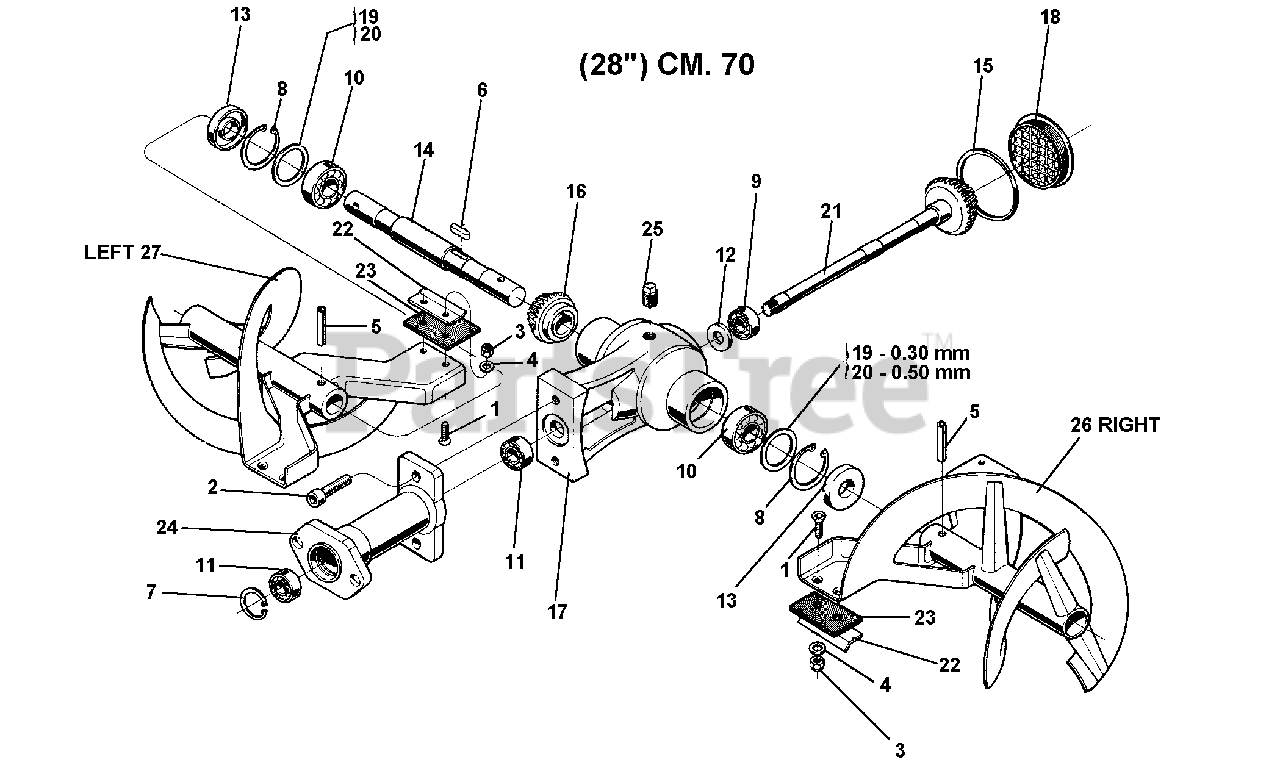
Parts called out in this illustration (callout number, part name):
1	SCREW M6 X 25
2	SCREW TCCEI M14 X 45
3	NUT, SELF LOCKING M6
4	WASHER, FLAT 6.4
5	PIN, LOCKING 10 X 50 DIN 1481
6	FLAT KEY 10 X 30 X 8 ACC.
7	CIRCLIP, INTERN. D 47
8	CIRCLIP, INTERN D 62
9	BEARING 20 X 47 X 14 6204
10	BEARING 30 X 62 X 16 6206
11	BEARING 20 X 47 X 14 6204 2RS ST
13	SEAL, OIL 30 X 62 X 10 STANDARD
14	ROTARY HOE SHAFT
15	RUBBER GASKET
17	CENTRAL CASING OF SNOW THROWER
18	CENTRAL CASING CAP
19	SHIM 0.3 MM
20	SHIM 0.5 MM
21	P.T.O. PINION
23	RUBBER FLAP
24	P.T.O. COUPLING
26	RIGHT ROTARY HOE
27	LEFT ROTARY HOE
